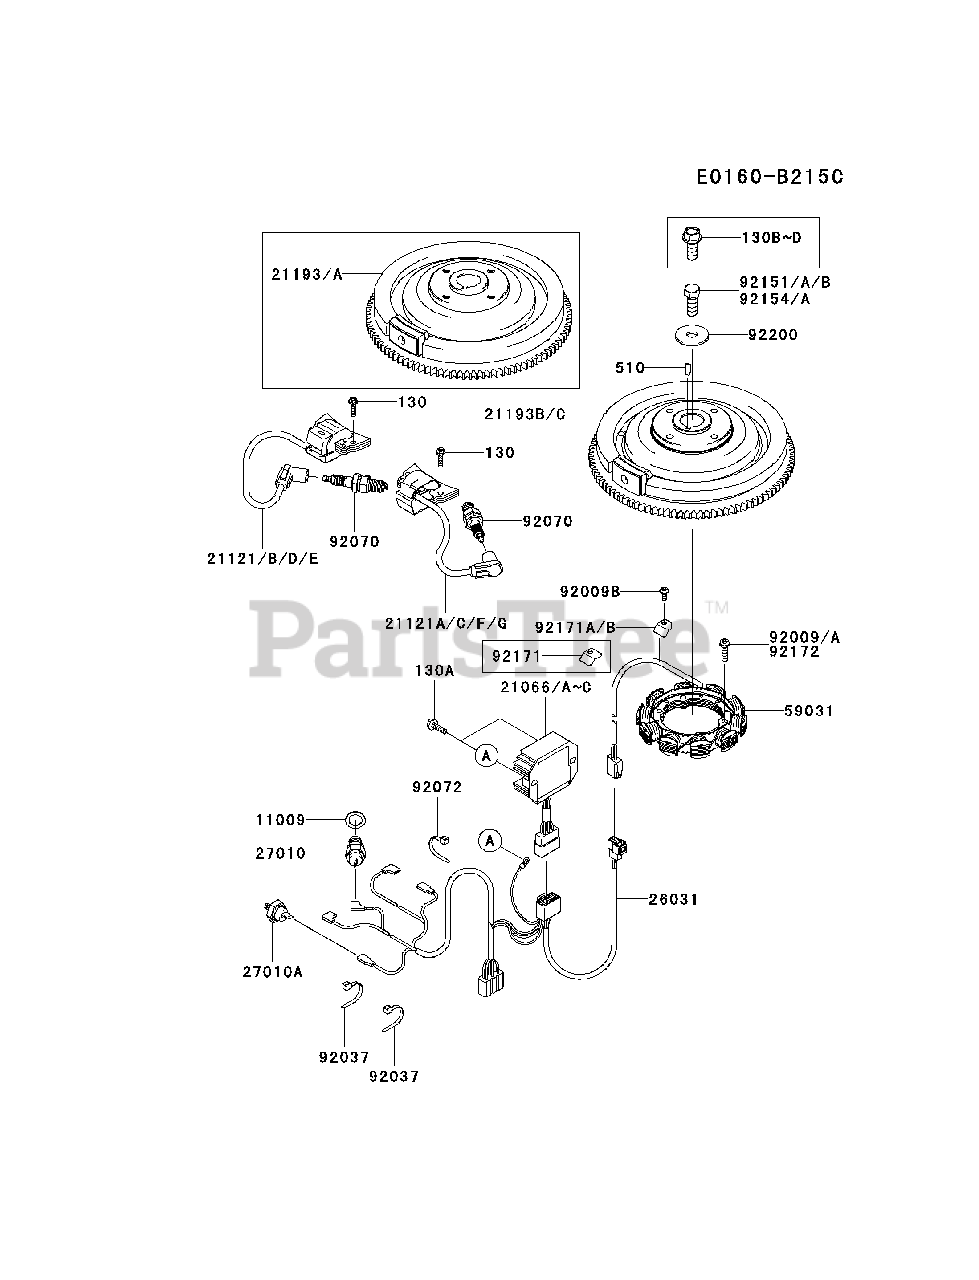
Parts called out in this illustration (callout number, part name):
130	BOLT-FLANGED,5X20
130A	BOLT-FLANGED,6X20
510	KEY-WOODRUFF
